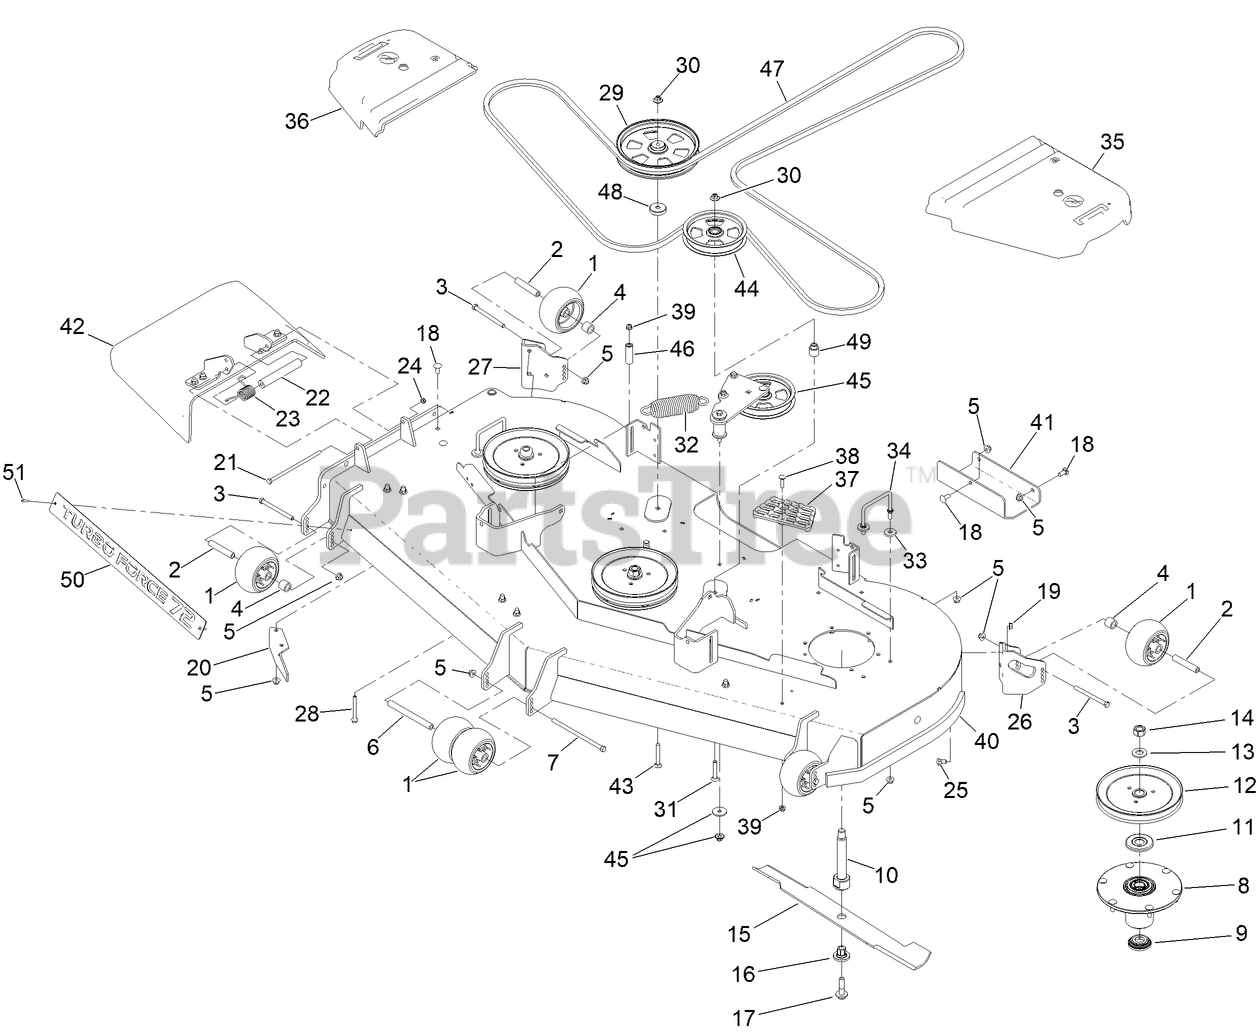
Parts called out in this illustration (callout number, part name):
1	ROLLER-SCALP, ANTI
2	TUBE-SPANNER
3	SCREW-HH
4	TUBE-SPACER
5	NUT-HF, NI
6	SPACER-WHEEL
7	SCREW-HH
8	SPINDLE ASM
9	GUARD-BOTTOM
10	SHAFT-SPINDLE
11	GUARD-BEARING, TOP
12	SHEAVE-DRIVE, BLADE
13	WASHER
14	NUT-HEX
16	BUSHING-HEX
17	SCREW-SEMS
18	SCREW-CARR
19	NUT-HHF, WHIZ
20	BAFFLE-DISCHARGE
21	SCREW-HH
22	SPACER
23	SPRING-TORSION
24	NUT-LOCK, NI
25	SCREW-CARR
26	MOUNT-WHEEL, LH
27	MOUNT-WHEEL, RH
28	SCREW-HHF
29	PULLEY-IDLER,FLAT
30	NUT-FLANGE, NI
31	SCREW-CARR
32	SPRING-EXTENSION
33	WASHER
34	WIREFORM-COVER
35	COVER-BELT, LH
36	COVER-BELT, RH
37	STEP-DECK
38	SCREW-CARR
39	NUT-HF, NI
40	DECK DECAL ASM
41	PLATE-SKID
42	RUBBER DEFLECTOR ASM
43	SCREW-CARR
44	PULLEY-IDLER, FLAT
45	IDLER ARM ASM
46	SPACER-HYDRO
47	BELT, V-5V X 206.6"
48	SPACER-PULLEY
49	BUSHING, IDLER
50	PLATE-TURBO FORCE [BLACK]
51	RIVET-TRIFOLD
